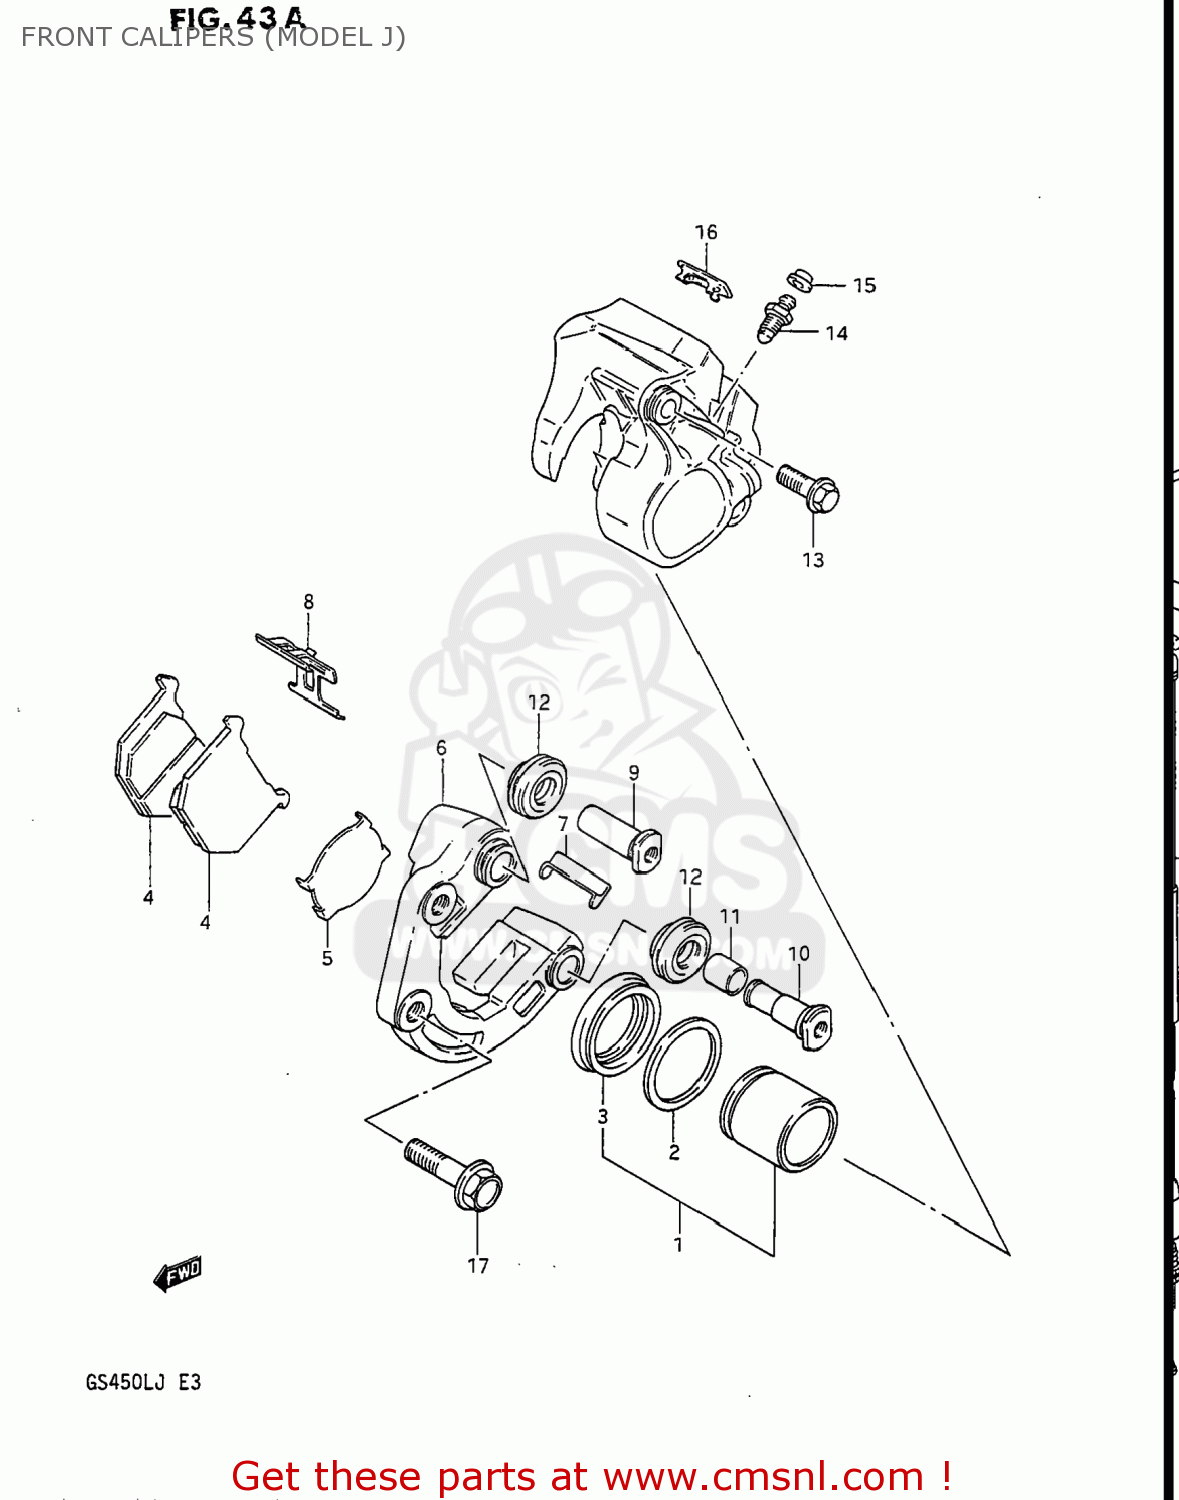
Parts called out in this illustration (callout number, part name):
1	PISTON SET
2	SEAL,FR CALIPE
3	BOOT,PISTON
4	PAD
5	SHIM,PAD
6	CARRIER,CALIPER,LEFT
7	GUIDE,PAD
8	SPRING,PAD
9	AXLE NO.1
10	AXLE NO.2
11	BUSH,AXLE
12	BOOT,AXLE
13	BOLT
14	BLEEDER
15	CAP,BREATHER
16	COVER
17	BOLT(10X37)
